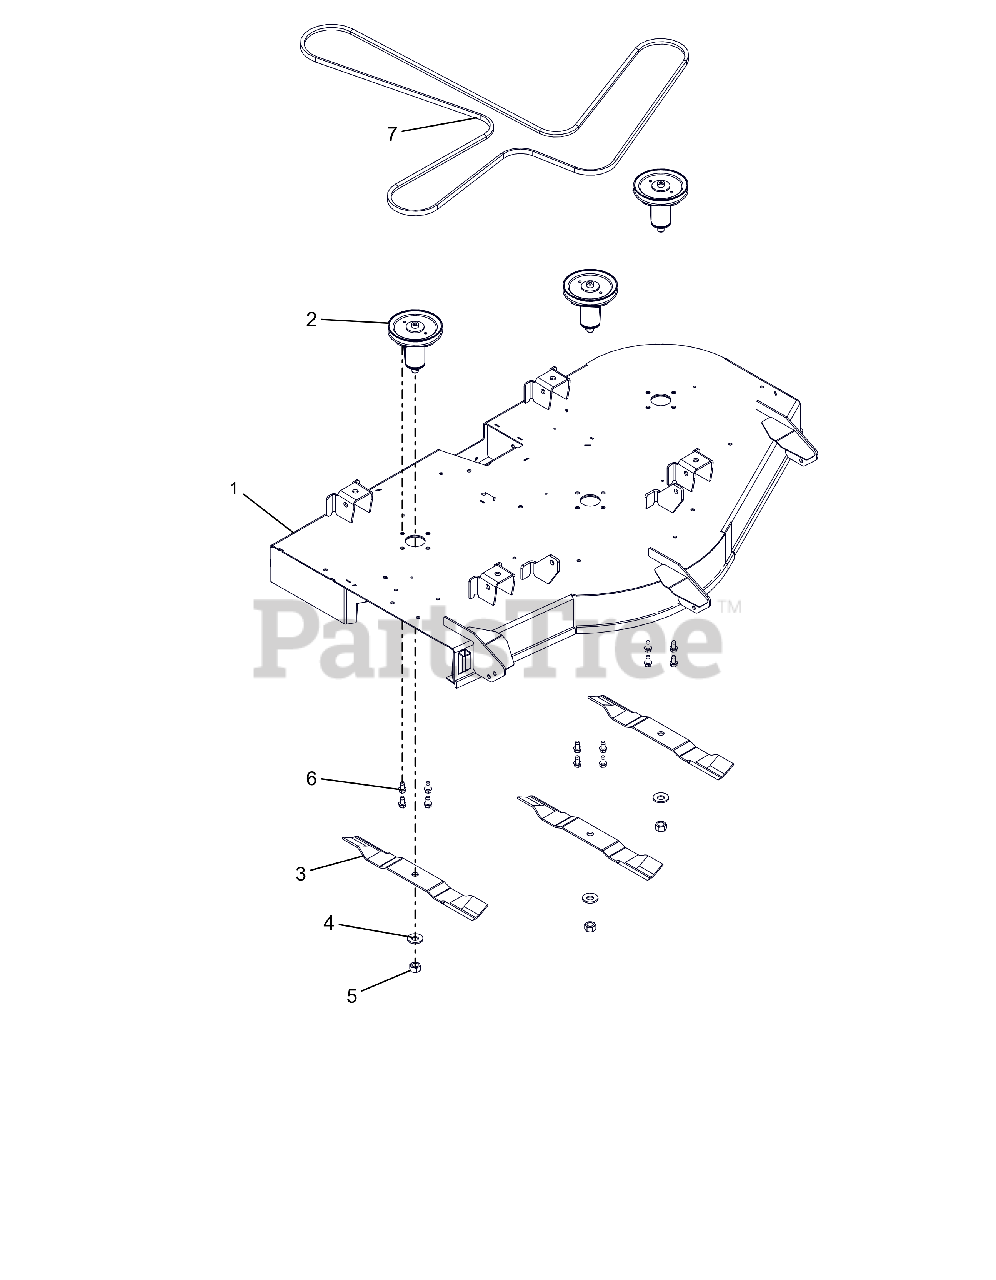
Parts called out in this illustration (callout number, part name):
1	KIT, 52" ARIENS DECK W/DECALS
2	KIT, DECK SPINDLE ASM-52
3	BLADE, 18" - 30 DEG .5 OFFSET
4	WSHR-BLVL .669X1.535X.138
5	NUT-STD .625-18 ZCC
6	SCR,TAP .375-16X.75 HWH TR ZCC
7	V-BELT, HA-WRAPPED
